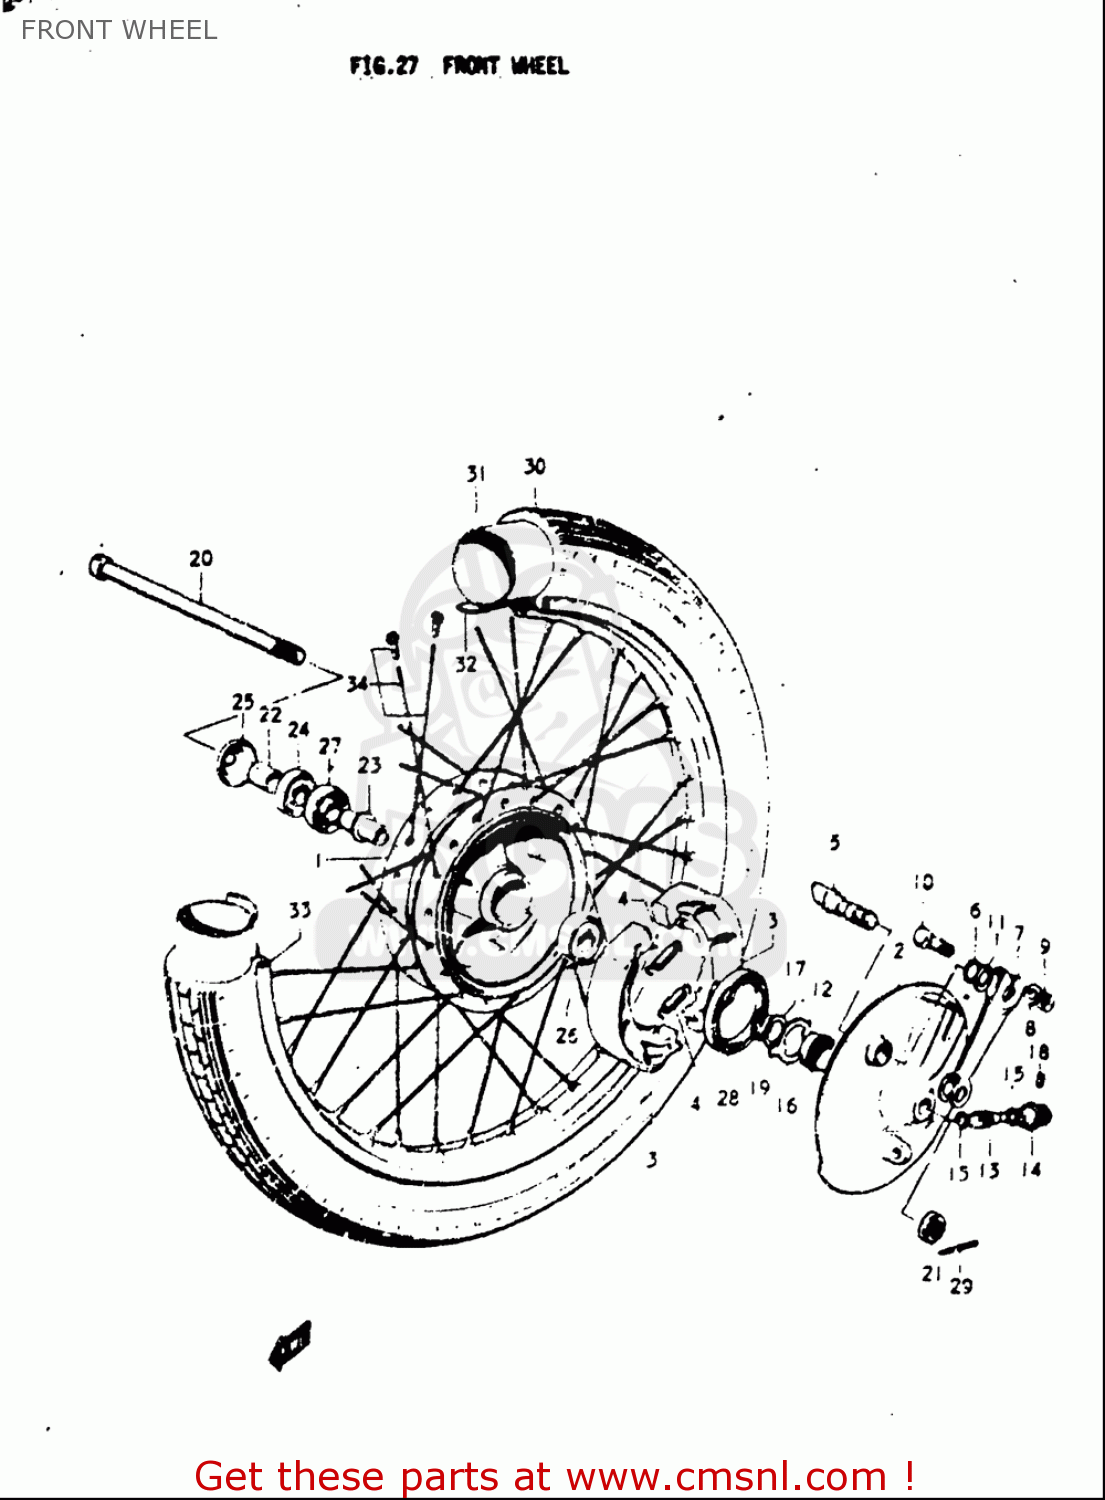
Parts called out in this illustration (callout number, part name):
1	HUB,FR WHEEL
4	SPRING(L:35.8)
5	CAM,FR BRAKE
6	O RING(D:2.5,ID:11.4)
7	LEVER,FR BRAKE CAM
8	WASHER
9	NUT
10	BOLT(6X31)
11	WASHER(12.5X20X1)
15	WASHER(5.1X9X0.4)
16	DRIVER,SPEEDOMETER GEAR
17	WASHER(18.5X24X1)
18	SCREW
19	CIRCLIP
20	AXLE,FR
21	NUT 12MM
22	SPACER(12X18X19.4)
24	OIL SEAL(17X38X5)
26	BEARING
27	BEARING
28	SEAL,OIL(48X62X7)
29	PIN
30	TIRE,FR(2.50-18 40L NF2)
32	PROTECTOR,INNER TUBE
33	RIM,WHEEL(1.40X18)
34	SPOKE SET,FR
